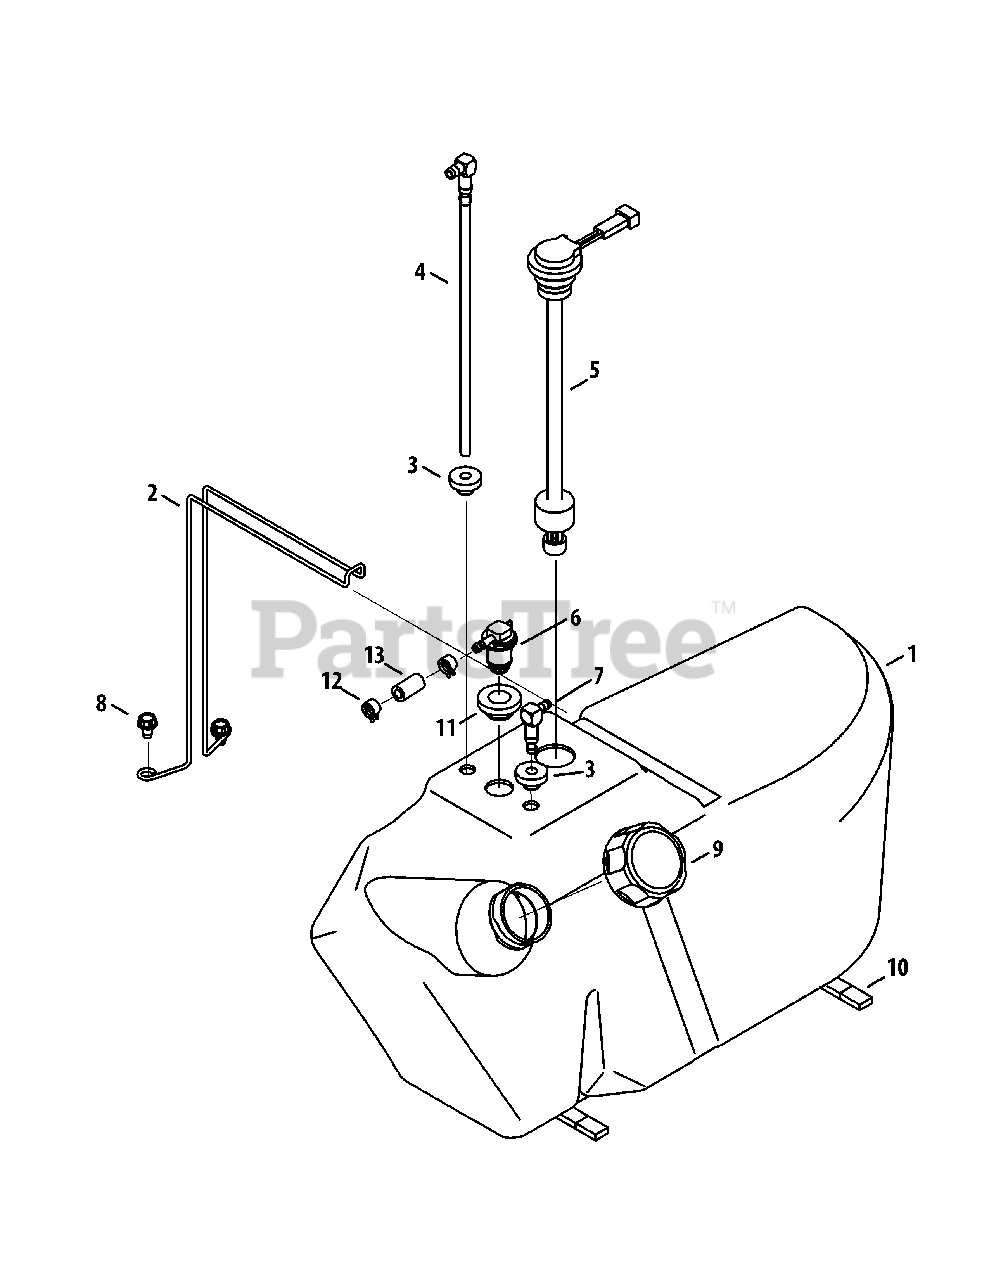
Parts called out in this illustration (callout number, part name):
1	Tank assembly, Fuel
2	Wire, tank, fuel
3	Bush, Tank, Gas
4	Fitting, Fuel, Pickup
5	Sensor, Fuel, Low
6	Fitting, Fuel, Vent
7	Fitting, Fuel, Pickup
8	Screw, 5/16-18 x .500
8	Screw, 5/16-18 x .75
9	Cap, Fuel
10	Tape, .75 Wide x.25 Thk Foam
11	Bush, Tank, Vent
12	Clamp, Hose, .490 Dia.
13	Fuel Line, 5/16 Id
